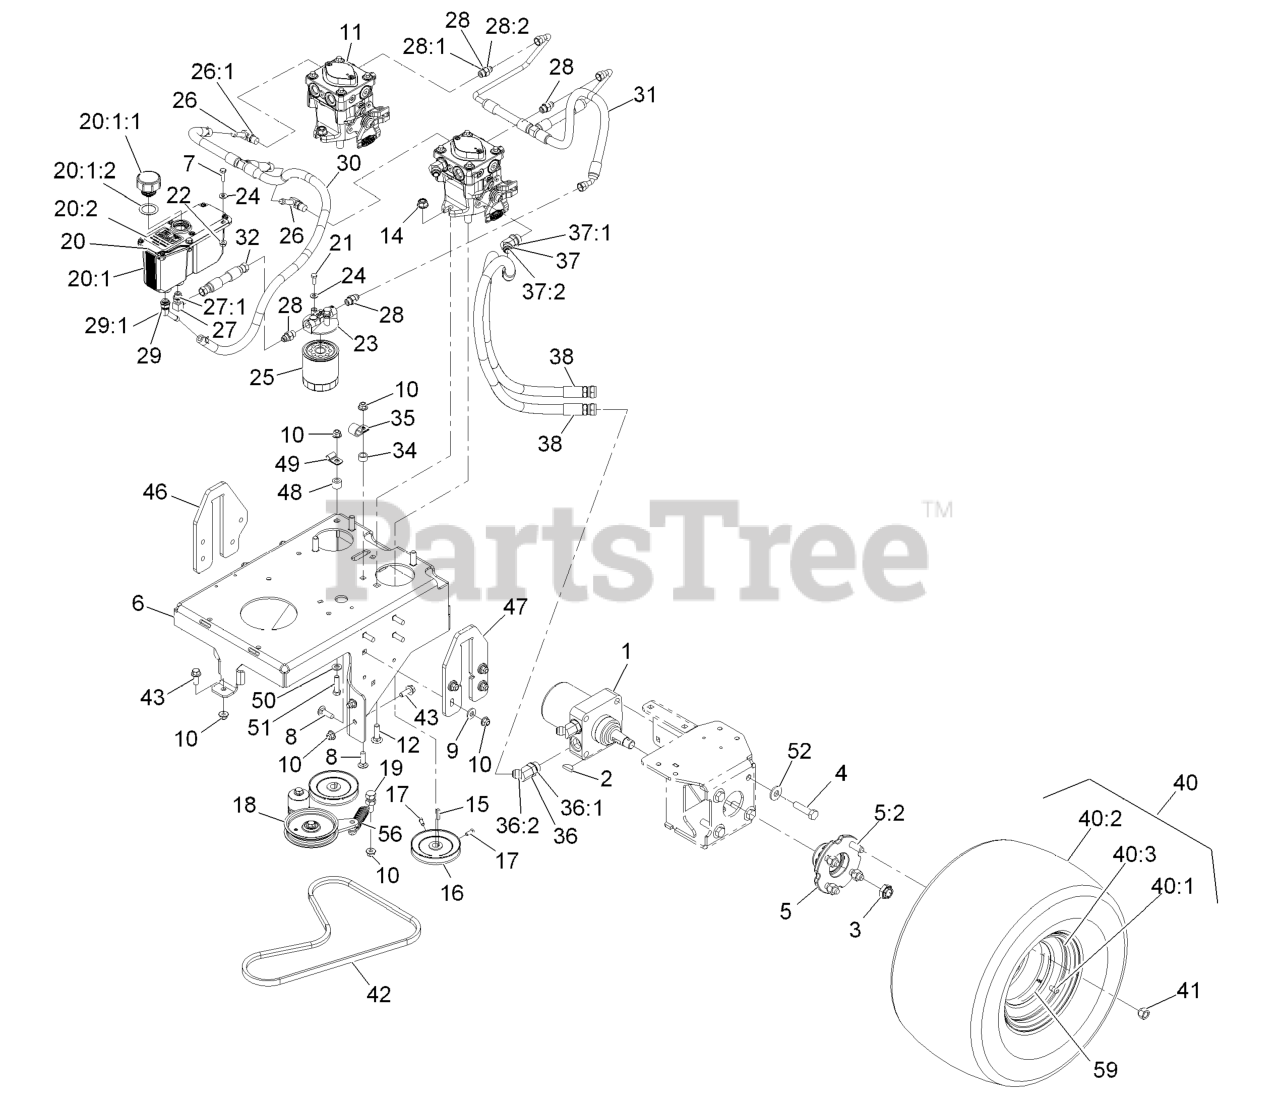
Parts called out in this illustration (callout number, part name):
1	MOTOR-WHEEL
2	KEY-WOODRUFF
3	NUT-LOCK
4	SCREW-HH
5	WHEEL HUB ASM
5:2	STUD-TYPE, DRIVE
7	SCREW-HH
8	BOLT-CARR
9	WASHER-BELLEVILLE
10	NUT-HF, NI
11	PUMP - HYDRAULIC
12	SCREW-HH
14	NUT-HF, NI
16	PULLEY-PUMP
17	SCREW-SET
18	PUMP IDLER ASM
20	RESERVOIR ASM
20:1	Reservoir-Hyd
20:1:1	Cap-Reservoir, HYD
20:1:2	GASKET-CAP
20:2	DECAL-HYDRAULIC TANK
21	SCREW-HH
22	NUT-HHF
23	HEAD-FILTER
24	WASHER-FLAT
25	FILTER-25 MICRON, BI-DIRE
26	FITTING-ELBOW, 90
26:1	O-RING
27	FITTING-ELBOW, 90 DEG
28	FITTING-STRAIGHT
29	FITTING-BARBED, 45 DEG
29:1	O-RING
30	TANK HOSE ASM
31	HOSE ASSEMBLY - CHARGE
32	HYD HOSE ASM
34	SPACER-WHEEL
35	CLIP-LOOM
36	FITTING-HYD, 45 DEG
37	FITTING-HYD, 45 DEG
40	WHEEL ASM
40:1	Stem-Valve
40:3	RIM-8 INCH
41	NUT-LUG
42	BELT-V, LOWER PTO
43	SCREW-HHF 3/8-16 X 1
46	PLATE-LIFT, RH
47	PLATE, LIFT LH
48	SPACER-PIVOT
49	CLIP-TUBE
50	WASHER-FLAT
51	SCREW-HH
52	WASHER-SPRING
56	SPRING-EXTENSION
